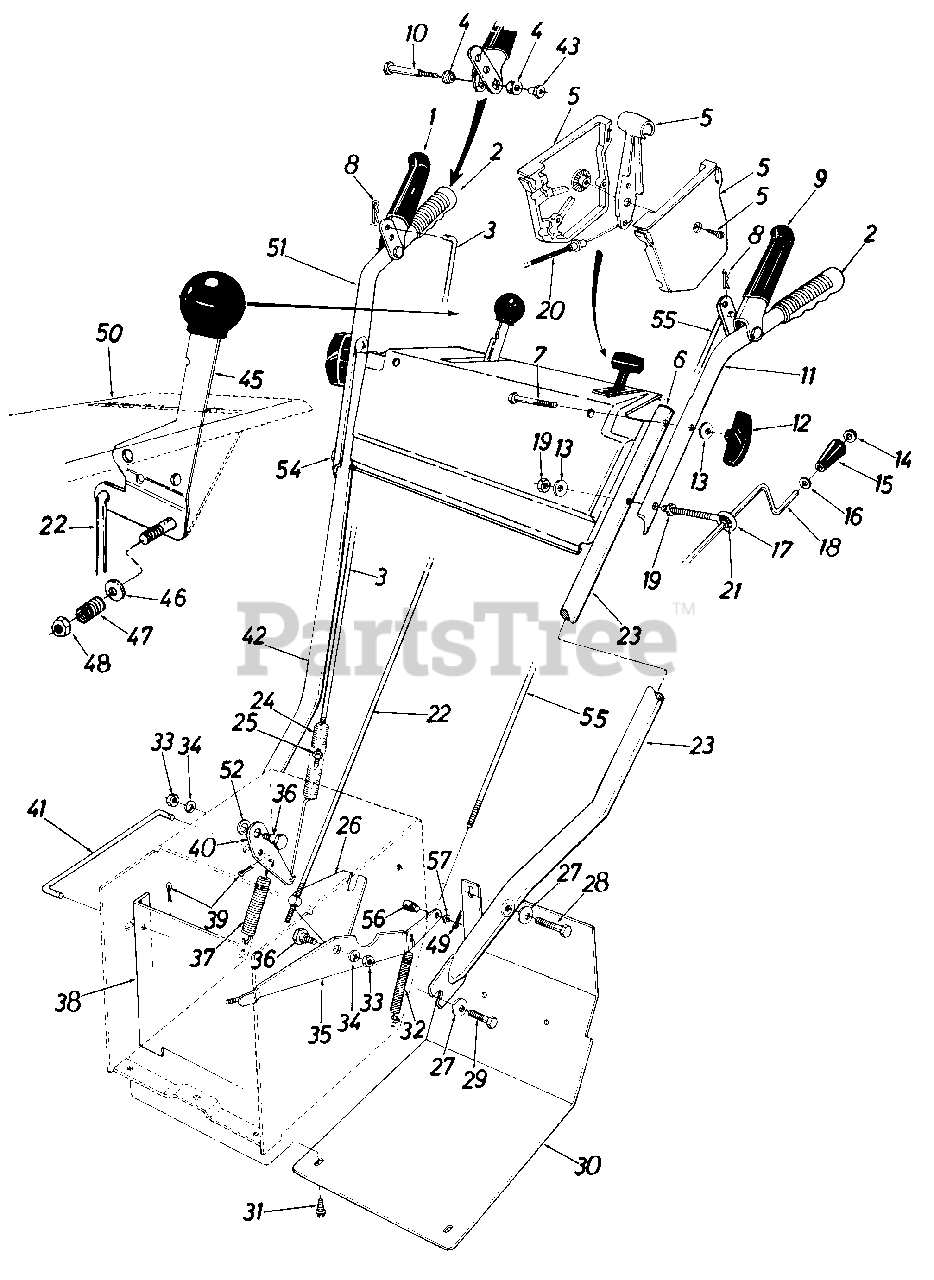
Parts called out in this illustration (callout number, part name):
1	Clutch Grip Ass'y. R.H.
2	Hand Grips
3	Lockout Cable 30.5" Lg.
4	Hex Flange Brg. Plastic .38" I.D.
5	Throttle Control Box Ass'y.
6	Plastic Plug
7	Hex Bolt 5/16-18 x 2.0" Lg.
8	Cotter Pin 3/32" Dia.
9	Clutch Grip Ass'y. L.H.
10	Shld. Bolt .374" Dia. x 1.53" Lg.
11	Upper Handle Half L.H.
12	Hand Knob
13	Belleville Wash. 5/16" I.D.
14	Push Nut 3/8" Rod
15	Knob 3/8" I.D.
16	Fl-Wash. .40 I.D. x .62 O.D. x .060
17	Eyebolt
18	Chute Crank Ass'y.
19	Hex Nut 5/16-18 Thd.
20	Throttle Wire 34" Lg.
21	Chute Crank Grommet
22	Shifting Rod
23	Lower Handle Half L.H.
24	Extension Spring .75" O.D. x 5.0" Lg.
25	Hex Ins. L-Nut 1/4-20 Thd.
26	Shifting Linkage Bracket
27	Belleville Wash. .40 I.D. x .88 O.D. x .060
28	Hex Bolt 3/8-16 x 2.0" Lg.
29	Hex Wash. Hd. Self-Tap Scr. 3/8-16 x .75" Lg.
30	615 Frame Cover
31	Hex Wash. Hd. Self-Tap Scr. 1/4-20 x .50" Lg.
32	Extension Spring .38" O.D. x 3.25" Lg.
33	Hex Jam Nut 3/8-16 Thd.
34	L-Wash. 3/8" I.D.
35	Auger Clutch Brkt. Ass'y.
36	Shld. Bolt .625" Dia. x .170" Lg.
37	Extension Spring .38" O.D. x 3.25" Lg.
38	Drive Pulley Support Brkt. Ass'y.
39	Cotter Pin 3/32" Dia. x .75" Lg.
40	Drlve Clutch Brkt.
41	Drive Clutch Rod
42	Lower Handle Half R.H.
43	Shld. Nut 1/4-20 Thd.
45	Shift Handle Ass'y.
46	Hex Ins. Jam L-Nut 3/8-24 Thd.
47	Compression Spring .38" O.D. x .88" Lg.
48	Bell-Wash. .40 I.D. x .88 O.D. x .060
49	Cotter Pin 3/32" Dia. x .75" Lg.
50	Handle Panel Ass'y.
51	Upper Handle Half R.H.
52	Bell-Wash. .38 I.D. x 1.12" O.D. x .02
54	Carriage Bolt 5/16-18 x 2.50" Lg.
55	Lockout Cable 36" Lg.
56	Adjustment Ferrule
57	Fl-Wash. .33" I.D. x .63" O.D.
